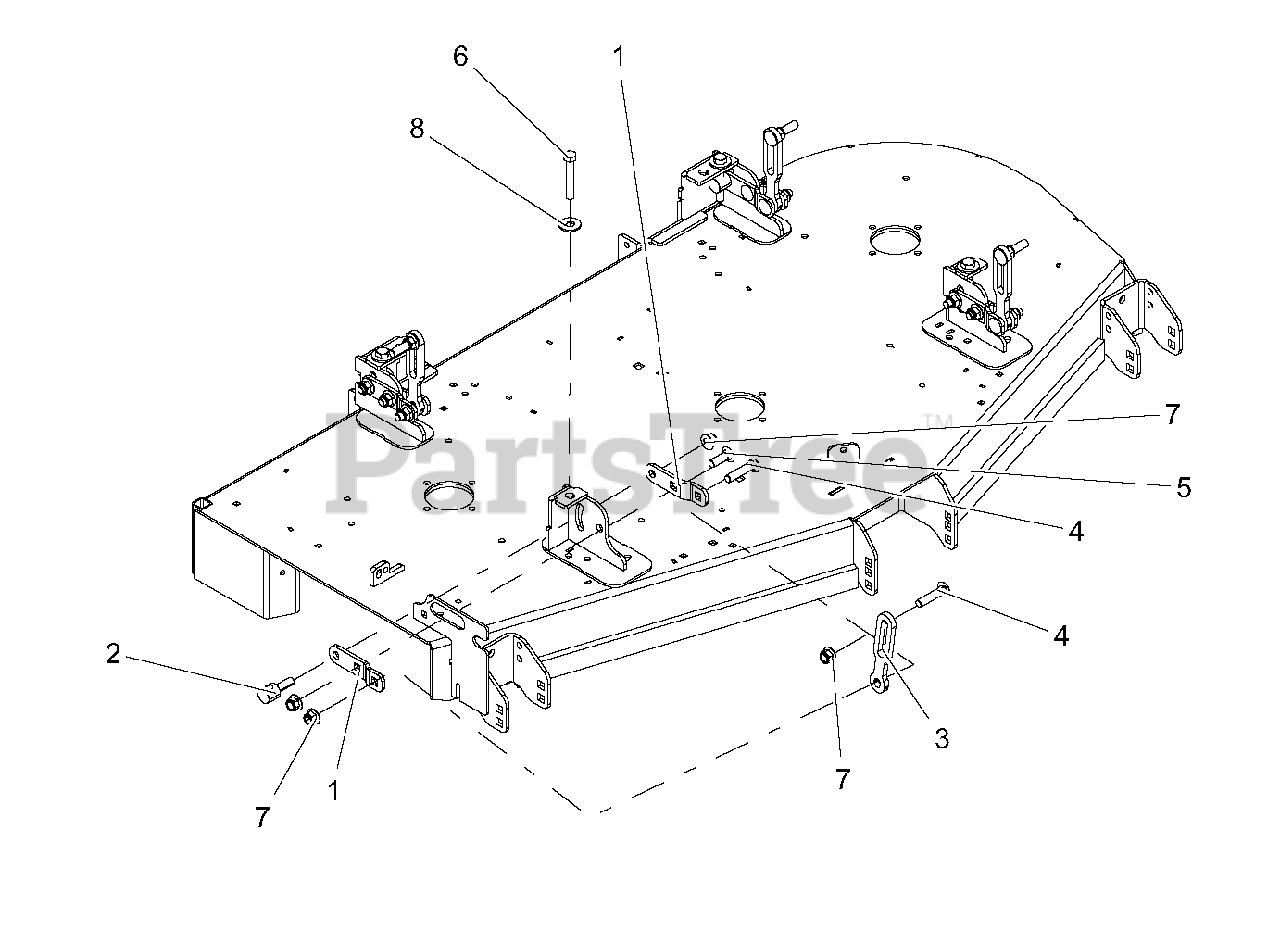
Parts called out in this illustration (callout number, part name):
1	BRKT, DECK LEVELING-BLACK
2	TRUNNION, .50-13
3	LINK, DECK LIFT
4	BLT-RDHDSQNK .50-13X2.25 G5 Y
5	@BLT-RDHDSQNK .50-13X1.50 G5 YWZC
6	BLT-HEX .50-13X3.00 GR5 FTH YZ
7	NUT-LK-NYL-FLG .50-13 YWZC
8	@WSHR-FL-STL.563X1.38X.109YWZC
